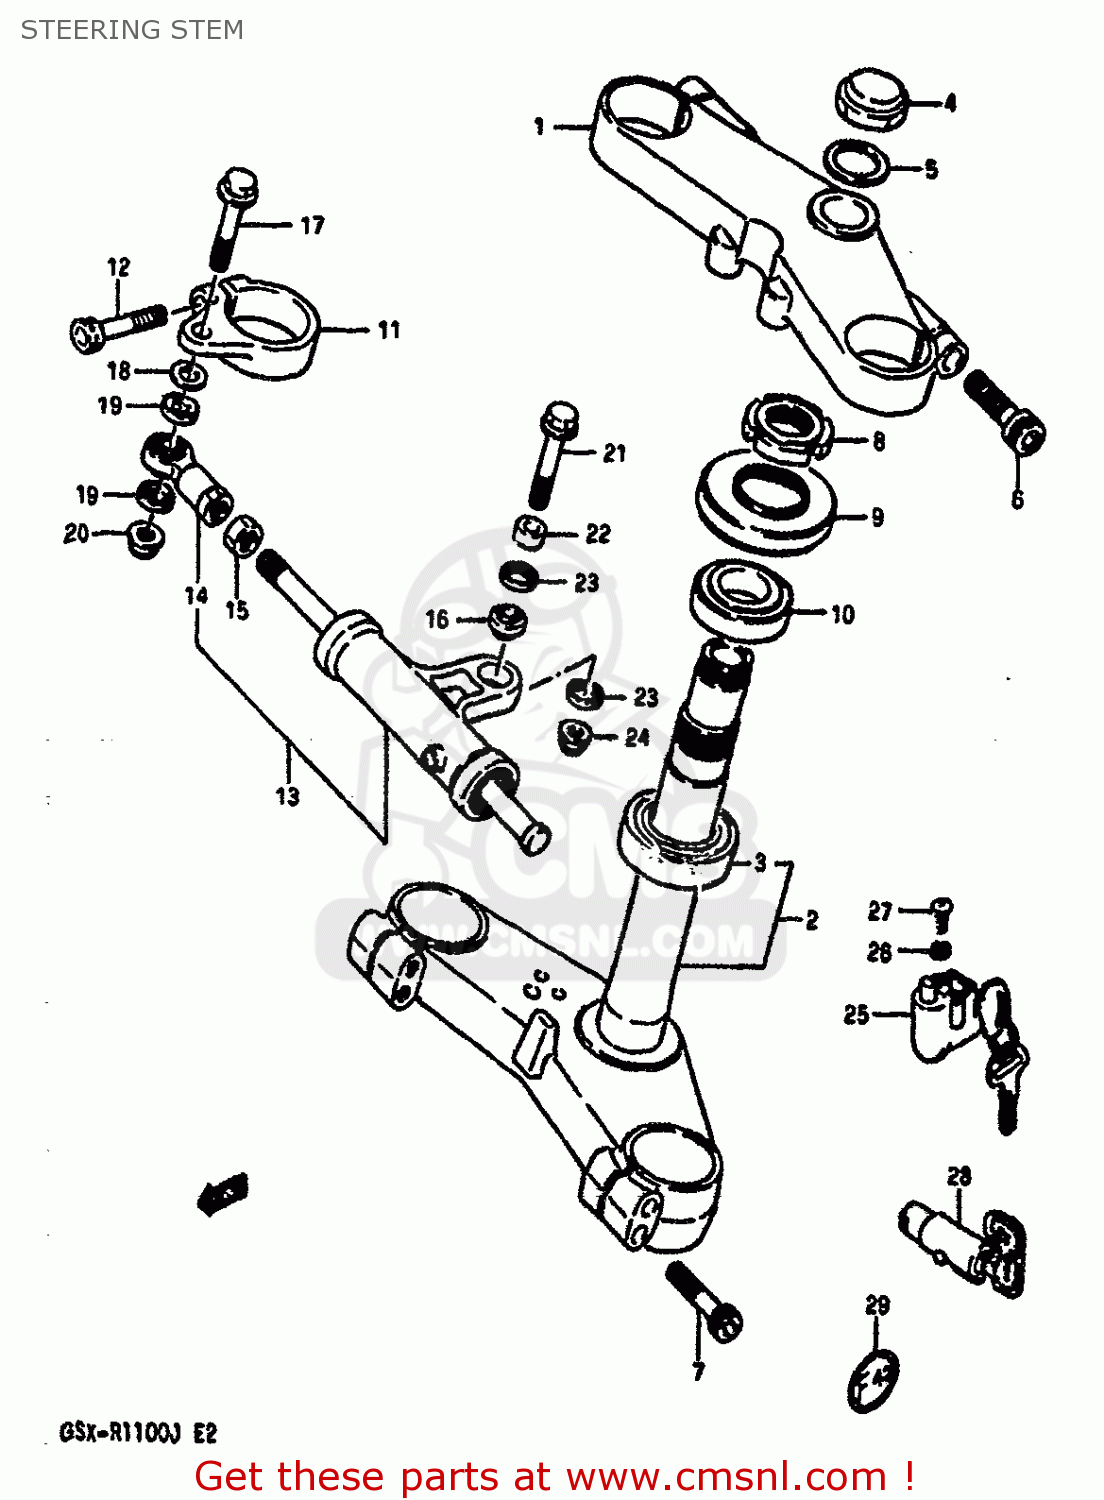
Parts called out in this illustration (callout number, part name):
1	STEM HEAD,STEERING
2	STEM,STEERING
3	BEARING
4	NUT,STEM HEAD
5	WASHER,STEERING STEM
6	BOLT,FORK INNER TUBE FITTING
7	BOLT
8	NUT,STEERING STEM(25X44X10)
9	SEAL OIL
10	TAPER,ROLLER BEARING
11	BRACKET,STEERING DAMPER
12	BOLT
13	DAMPER ASSY, STEERING
14	BEARING, LOD END
15	NUT
16	BEARING(8X18X11)
17	BOLT(8X33)
18	WASHER
19	20
20	NUT
21	BOLT(8X45)
22	SPACER (8.5X15X10)
23	24
24	NUT
25	LOCK ASSY,STEERING
26	LOCK WASHER
27	SCREW 5X20
28	LOCK ASSEMBLY,STEERING (NEI
29	LABEL,STEERING LOCK
